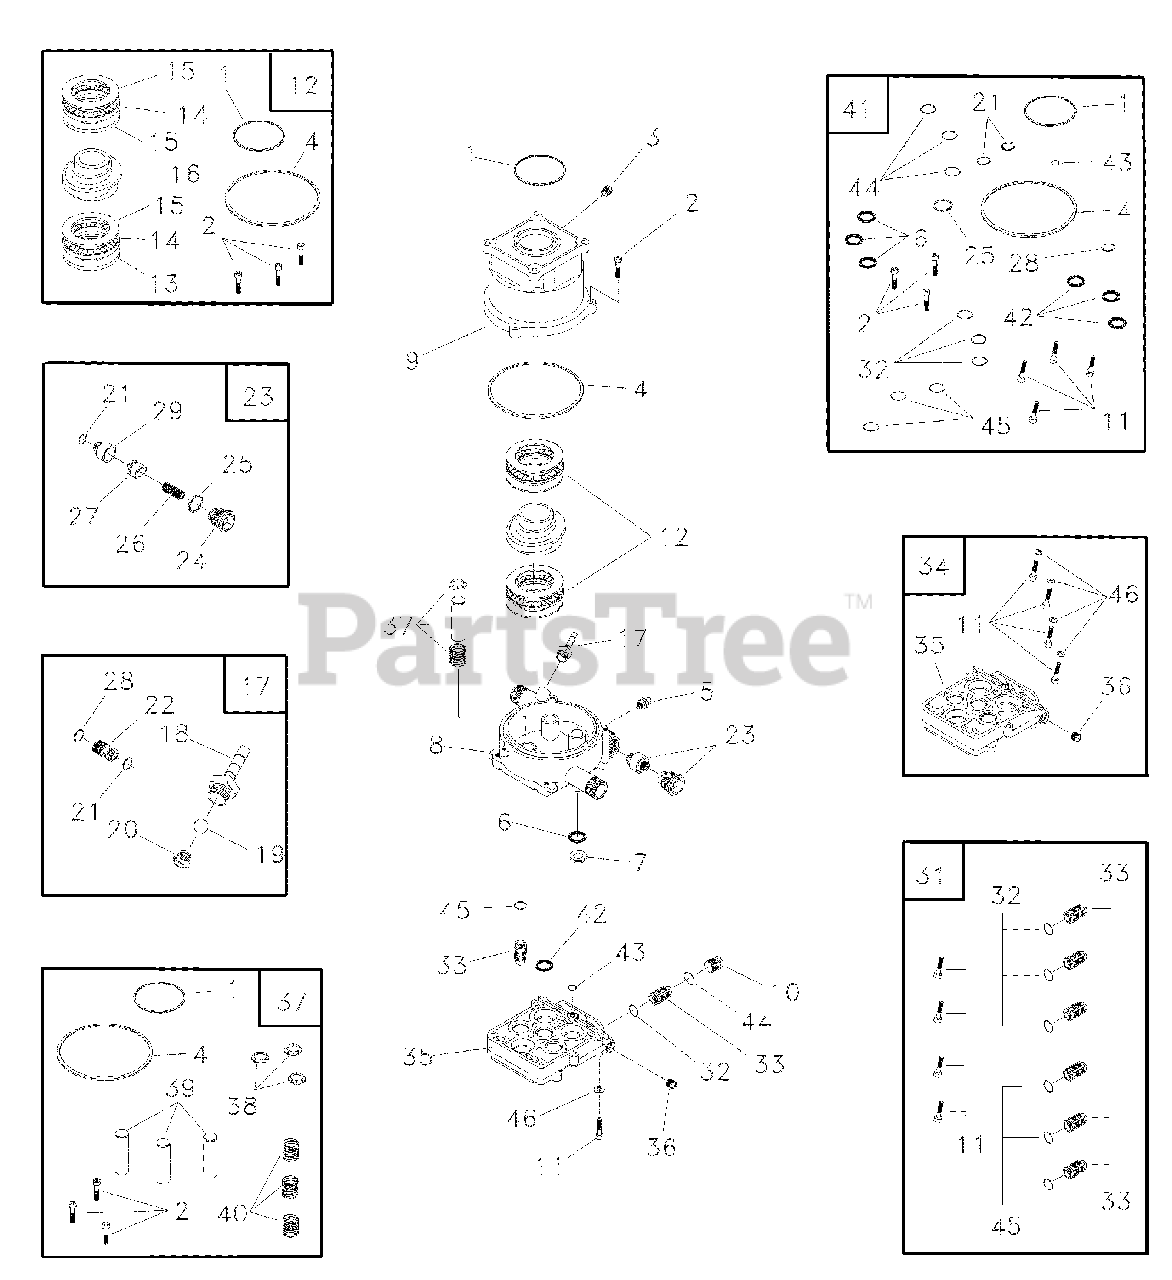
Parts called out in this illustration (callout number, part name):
1	O-RING, 1.625 ID x .103
1	O-RING, Engine Seal
2	SHCS, M6 - 1 x 25
3	VALVE, 1/8 npt 1-5 PSI
4	O-RING, Housing Seal
5	THERMAL RELIEF, GPW-EG
6	SEAL, Oil Piston
7	SPACER, Pilot
8	HOUSING, Piston
9	ADAPTER, Engine
10	CAP, Outlet Check Valve
11	SHCS, M6-1.0 x 35
12	KIT, AXIAL CAM
13	WASHER, Brg. 36 x 65 x 6Thk
14	ASSY., Brg. Cage 45 x 65
15	WASHER, Brg. 45 x 65 x 1
16	CAM, Axial 5.6 7/8"SAE
17	KIT, CHEM INJECT
18	FITTING, Chem Inject
19	BALL, Chem Inject
20	SPRING, Chem Inject
21	O-RING, Venturi & Seat, Black
22	VENTURI, Chem Inject
23	KIT, UNLOADER 2300
24	CAP, Unloader
25	O-RING, Unloader Cap
26	SPRING, Unloader
27	PISTON, Unloader
28	O-RING, Venturi, Yellow
29	SEAT, Unloader
31	KIT, CHECK VALVES
32	O-RING, Check Valve
33	ASSY., Check Valve
34	KIT, HEAD BRASS EG
35	HEAD, Pump
36	PLUG, 1/8-28
37	KIT, PISTON & SPRING
38	RETAINER, Piston Spring
39	PISTON, Dia. 15 x 65 Lg
40	SPRING, Piston Return
41	KIT, O-RING/SEAL 2300
42	SEAL, Double-Lip
43	O-RING, High Pressure Transfer
44	O-RING, Outlet CV Cap
45	O-RING, Check Valve, White
46	WASHER, M6 Flat
